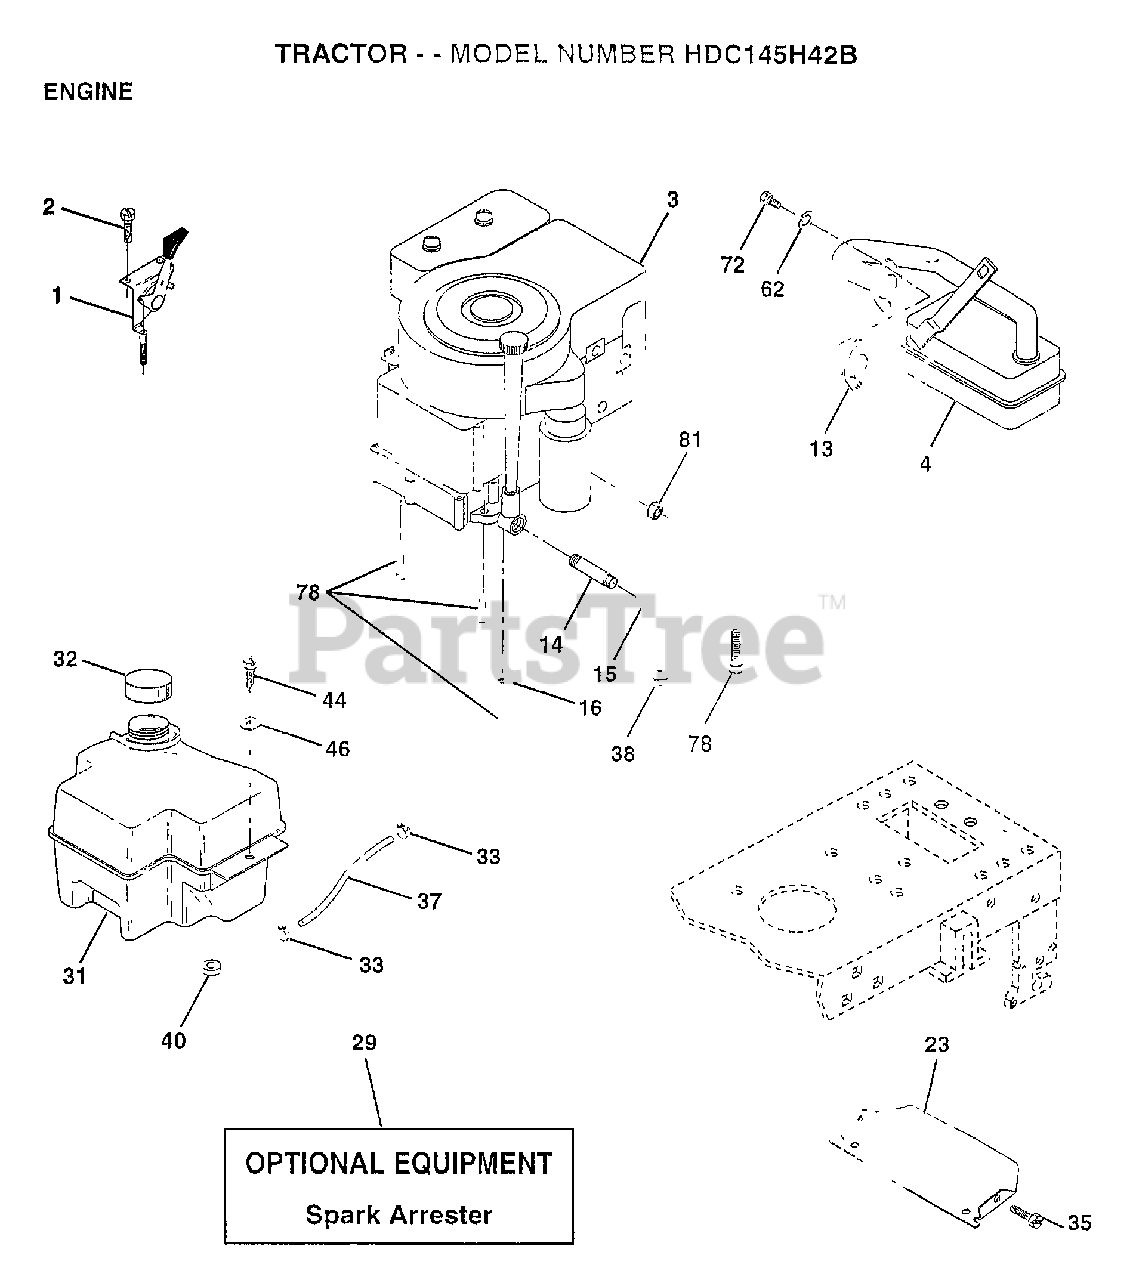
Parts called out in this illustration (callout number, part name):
1	CONTROL THROTTLE
2	SCREW LT
4	MUFFLER
13	GASKET ENG 1 313 LD TIN PLATED
14	PIPE NIPPLE
15	ELBOW
16	LOCKWASHER
23	SHIELD-HEAT
32	CAP ASM FUEL
33	HOSE CLAMP
35	SCREW
37	LINE FUEL
44	SCREW HEX CRT
46	WASHER
62	LOCKWASHER
72	SCREW
78	SCREW
81	NUT
